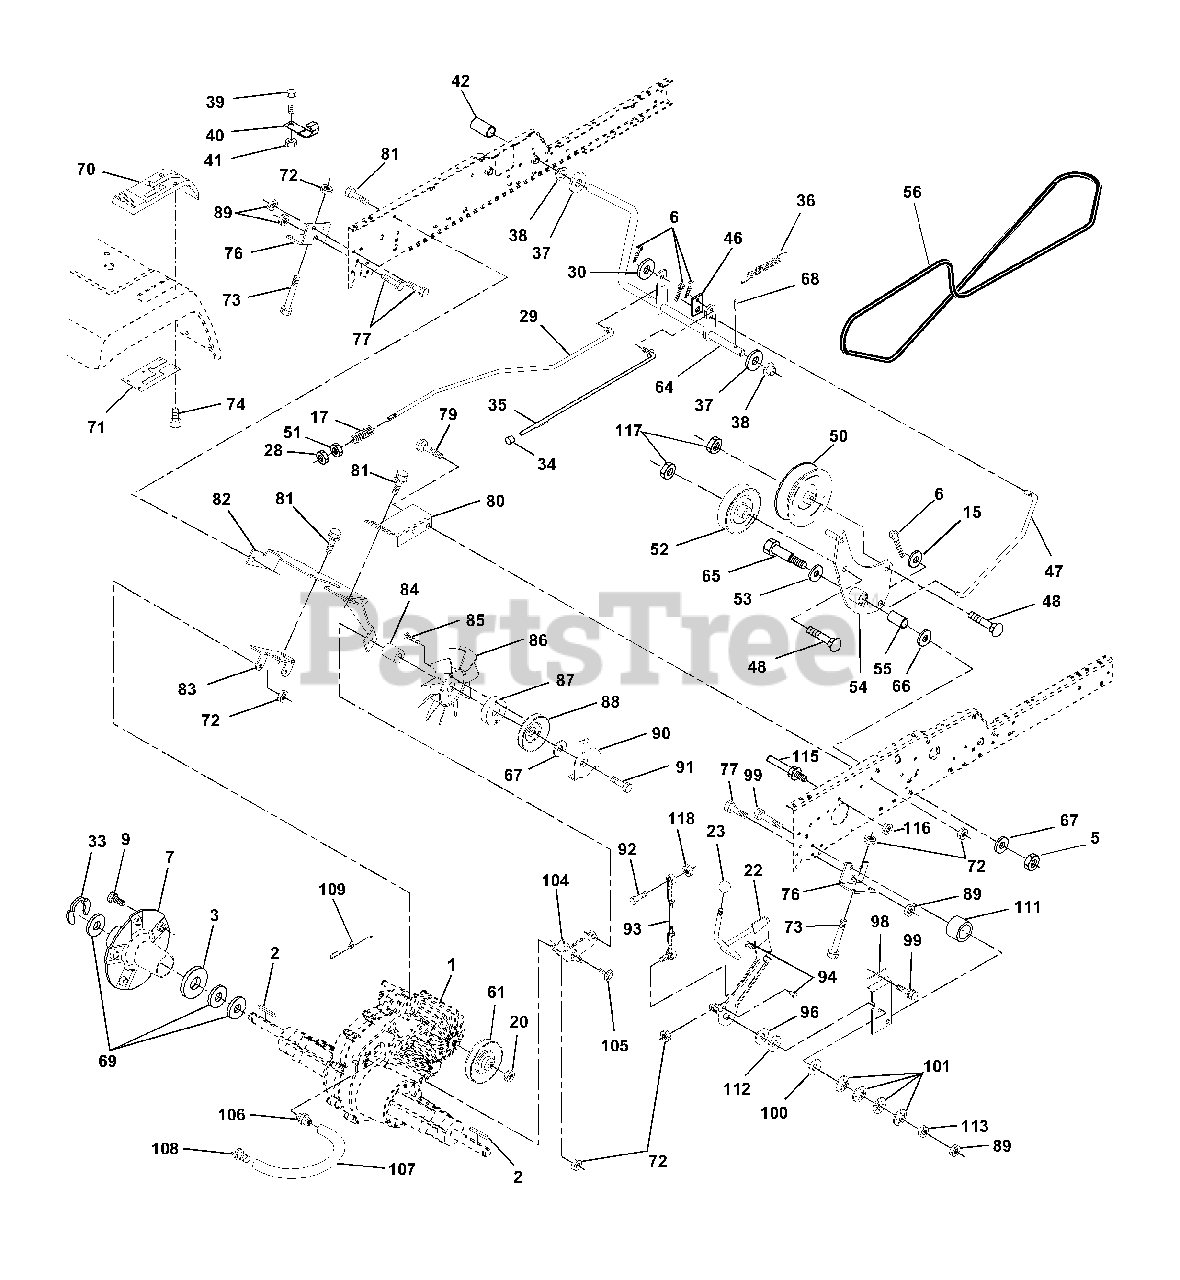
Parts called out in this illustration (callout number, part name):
2	Key 1/4 x 2.5
3	Washer Thrust Axle Harden
5	Nut Crownlock 3/8-16
6	Pin Cotter 1/8 x 3/4
7	Wheel Hub Asm.
9	Bolt Hub
15	Washer 13/32 x 13/16 x 16 Ga
17	Spring Rod Brake
20	Nut Hex Jam Toplock 1/2-20
22	Shift Arm Asm
23	Knob
28	Nut Hex Jam 3/8-16
29	Brake Rod
30	Washer 13/32 x 1 x 16 Ga.
33	Ring E
34	Cap Brake Parking
35	Rod Parking Brake
36	Spring Drive Ground
37	Washer 25/32 x 1-1/4 x 16 Gauge
38	Nyliner, Bushing
39	Screw Fin #10-24 x 1
40	Actuator Interlock Switch
41	Nut Lock #10-24
42	Cover Pedal
46	Retainer Spring
47	Clutch Rod
48	Bolt Carriage 3/8-16 x 1-1/2 Gr 5
50	Pulley Idler Flat
51	Nut Crownlock 3/8-16 UNC
52	Pulley Idler Grooved
53	Washer Hartdened
54	Clutch Arm Asm
55	Bearing, Idler
56	V-Belt
58	Bolt Fin Hex 7/16-14 x 1-1/2
61	Pullery Transaxle
64	Shaft Asm Brake Parking Clutch
65	Bolt Shoulder
66	Washer Hardened
67	Washer 13/32 x 13/16 x 12 Ga
68	Pin Roll
69	Washer
70	Console Hydro Fender
71	Plate Console Shift
72	Locknut Hex W/Washer Insert
73	Bolt Fin Hex 5/16-18 x 3
74	Screw Hex Wsh. Hi-Lo 1/4-1/2
76	Bracket Transaxle
77	Bolt Fin Hex 7/16-14 x 1
79	Bolt Carriage 5/16-18 x 5/8
80	Bracket Torque RH
81	Screw Thdrol 3/8-16 x 3/4
82	Bracket Mount Torque/Fan
83	Strap Torque Mid
84	Spacer
85	Screw #10-24 x 1-1/4
86	Fan 7" Hydro
87	Adapter Fan
88	Pulley Idler
89	Nut Crownlock 7/16-14 UNC
90	Keeper Belt
91	Screw Thdrol 3/8-16 x 2-3/4
92	Bolt Fin Hex 5/16-18 x 1.25
93	Link Shift Asm
94	Fastner Christmas Tree
96	Washer Nickel Plated
98	Bracket Shift
99	Screw Thdrol 3/8-16 x 1-1/2
100	Washer Compression
101	Washer Bellville
104	Bracket Idler
105	Screw Tap 1/4-20 x 1/2
106	O-Ring Asm Hydro Gear 70110
107	Line Fuel Hydro 15" VGT Serv
108	Cap Asm Vent Hydro Gear 70109
109	Spring Return Brake
111	Spacer Shift Lever VGTH
112	Washer Nylon High Temp
113	Nut Hex ASF 7/16-14 UNC
115	Keeper Belt T/A Gnd Dr LR
116	Nut Lock Hex Flange 5/16-18
117	Nut Lock Flg. 3/8-16 UNC
118	Nut Lock Hex w/Ins 5/16-18 UNC
